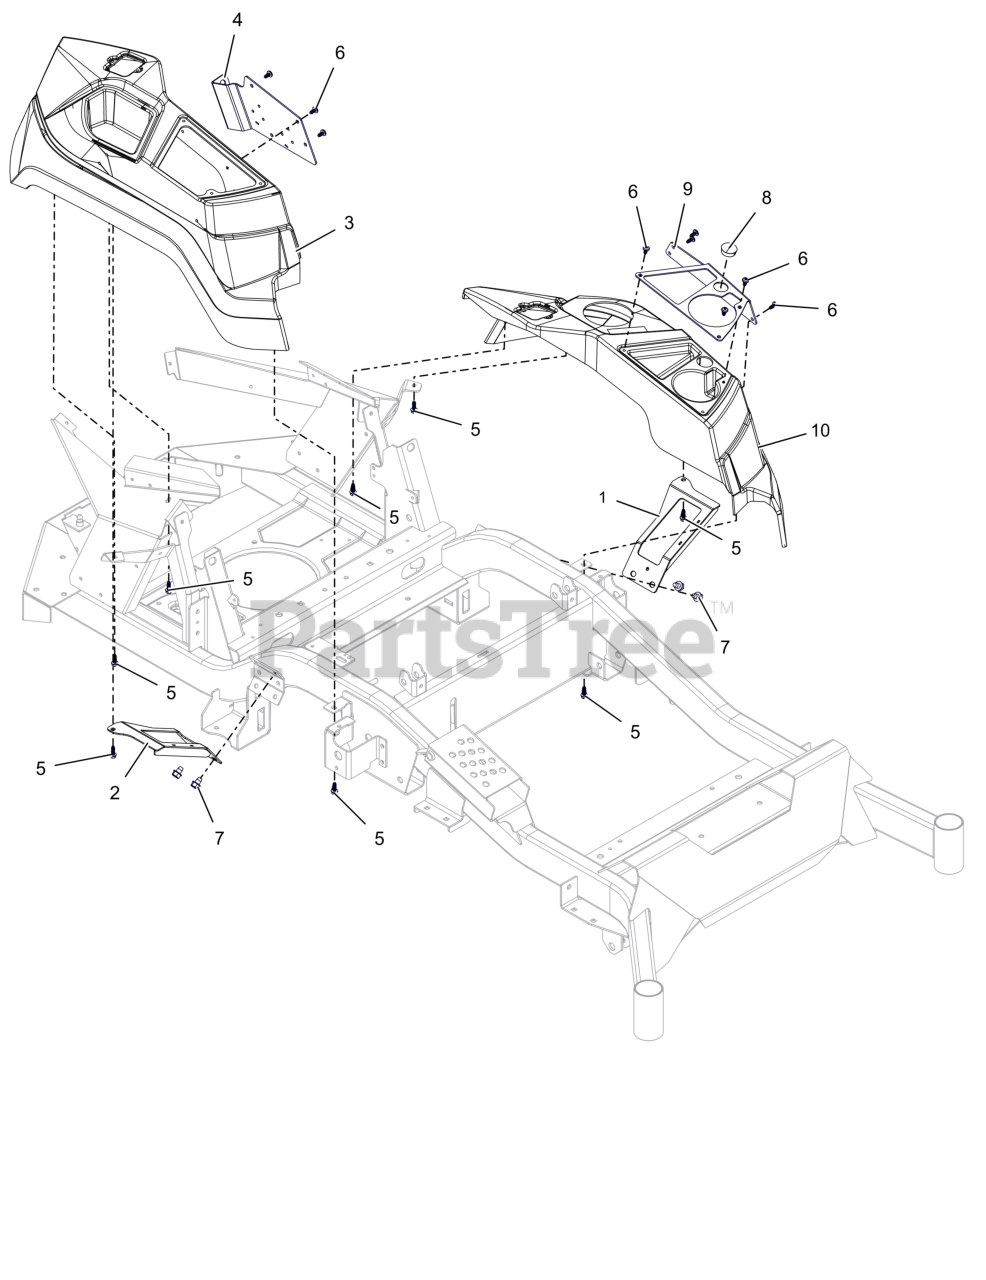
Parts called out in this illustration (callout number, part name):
1	WLDMT, LH FENDER MOUNT
2	WLDMT, RH FENDER MOUNT
3	FENDER, RH APEX - 2017
4	BRKT, FENDER/RELAY MOUNTING
5	SCR, PLASTITE .25-10X.75 ZCC
6	SCR-PAN .25-15X.50 6L H/LZB500
7	SCR,TAP .375-16X.50 HWH TR ZCC
8	PLUG, HOLE 1.125 DOMED
9	PLATE-APEX CUP HLDR W/USB(ORG)
10	FENDER, LH APEX
